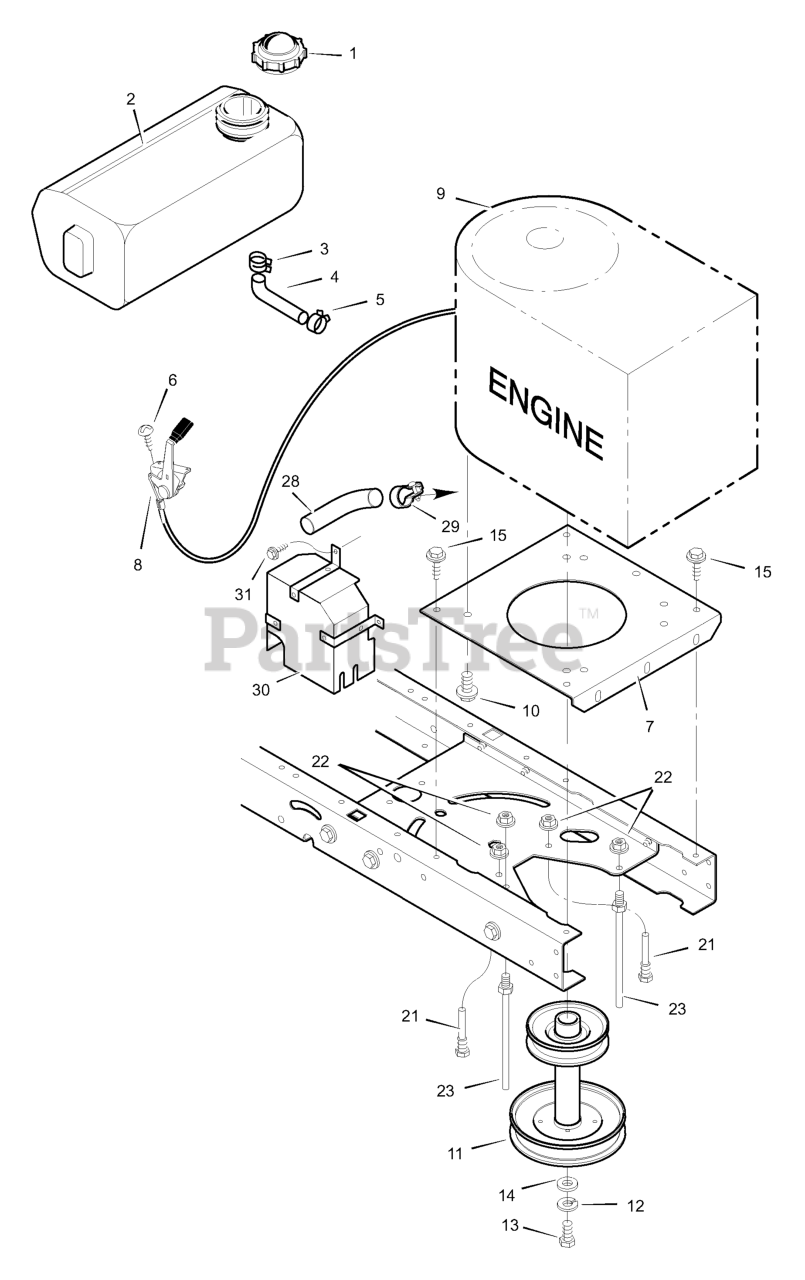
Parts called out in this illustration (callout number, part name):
1	Fuel Cap
2	Fuel Tank
3	Hose Clamp
4	Fuel Line
5	Hose Clamp
7	Plate, Engine
8	Throttle Control
9	Engine
10	Bolt, Engine Mount
11	STACK PULLEY ASSEMBLY
12	Lockwasher
13	Bolt, Hex
21	Guide, Belt
22	Nut, Flange
23	Guide, Belt
28	Pipe, Exhaust
30	Shield, Heat
